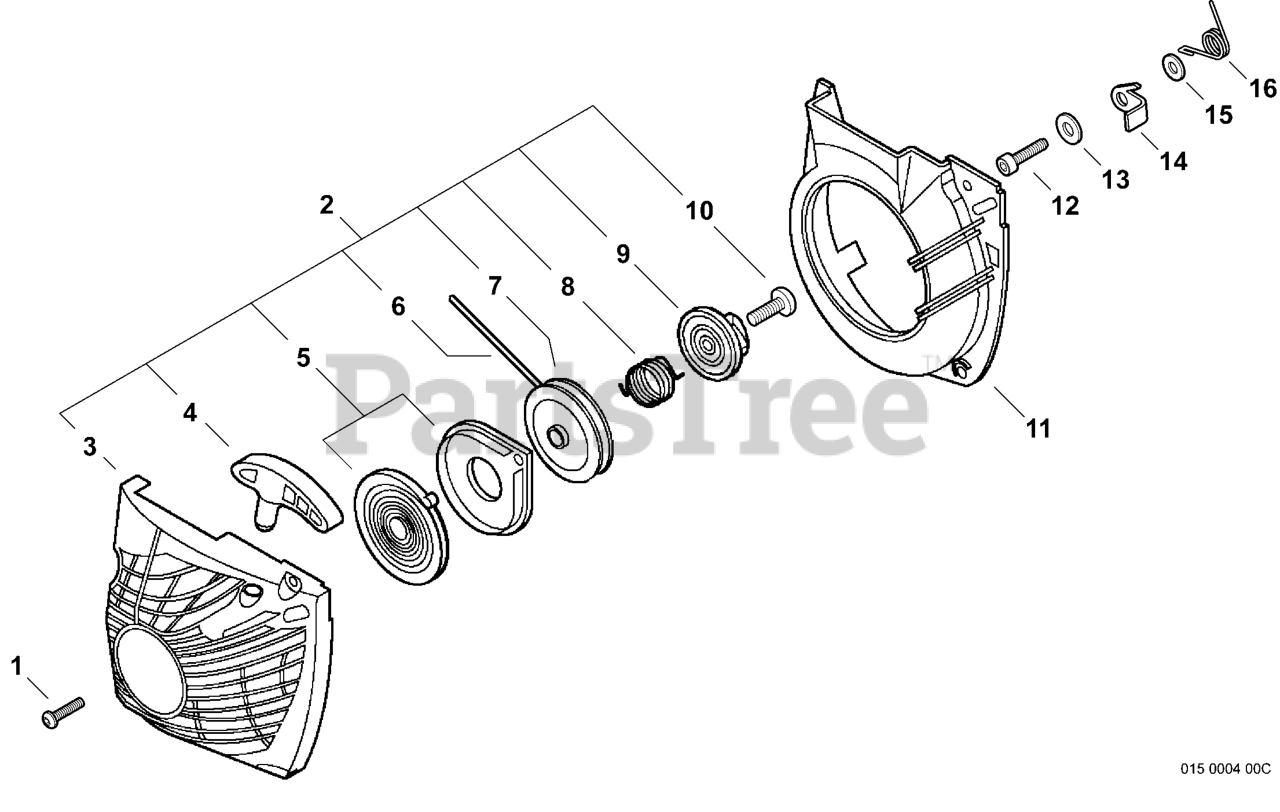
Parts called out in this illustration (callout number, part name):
1	SCREW, TAPPING 5x20
2	STARTER ASSY, RECOIL - I-START
3	CASE, RECOIL STARTER
4	GRIP, STARTER
5	SPRING SET, RECOIL
6	ROPE, STARTER 3.5x900
7	REEL, ROPE
8	SPRING, TORSION
9	PAWL CATCHER
10	SCREW
11	COVER, FAN
12	BOLT 5x14
13	WASHER 5.5x12x0.8
15	SPACER 5.2x8x2.1
16	SPRING, TORSION
